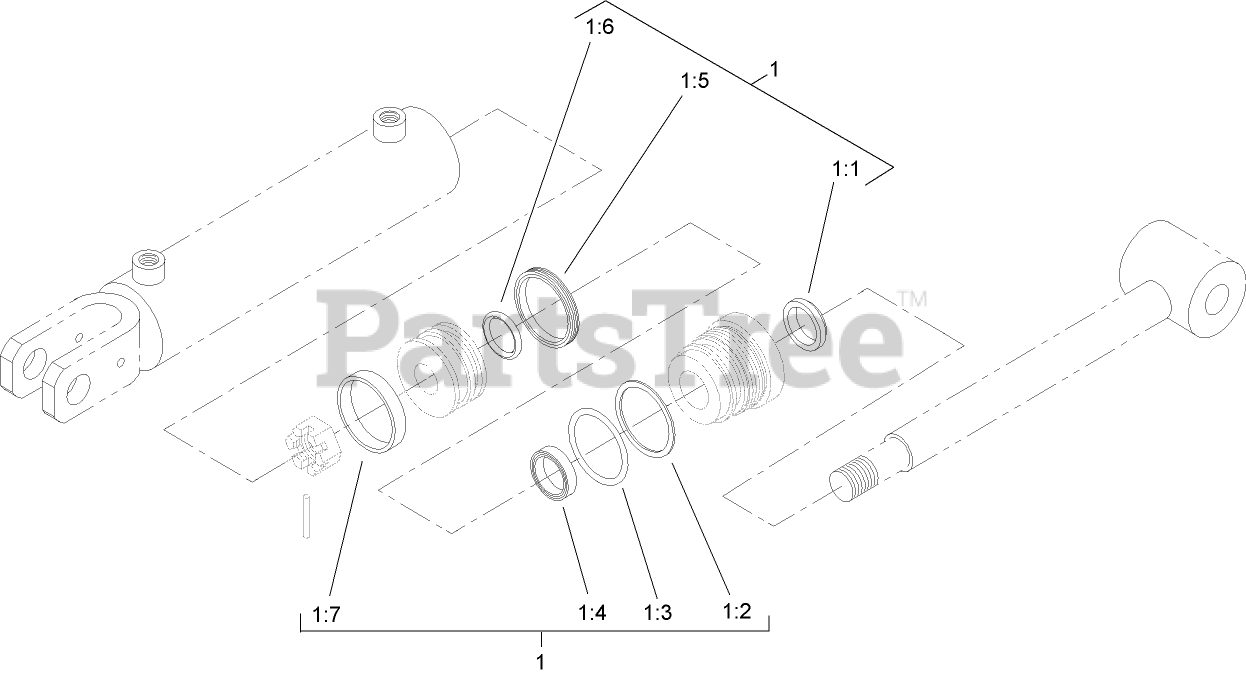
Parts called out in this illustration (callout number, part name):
1	KIT-SEAL
1:1	Seal-Shaft
1:2	Ring-Back Up
1:3	Seal-Dust
1:4	Seal ASM
1:5	Seal ASM
1:6	Seal-Dust
1:7	Wiper
